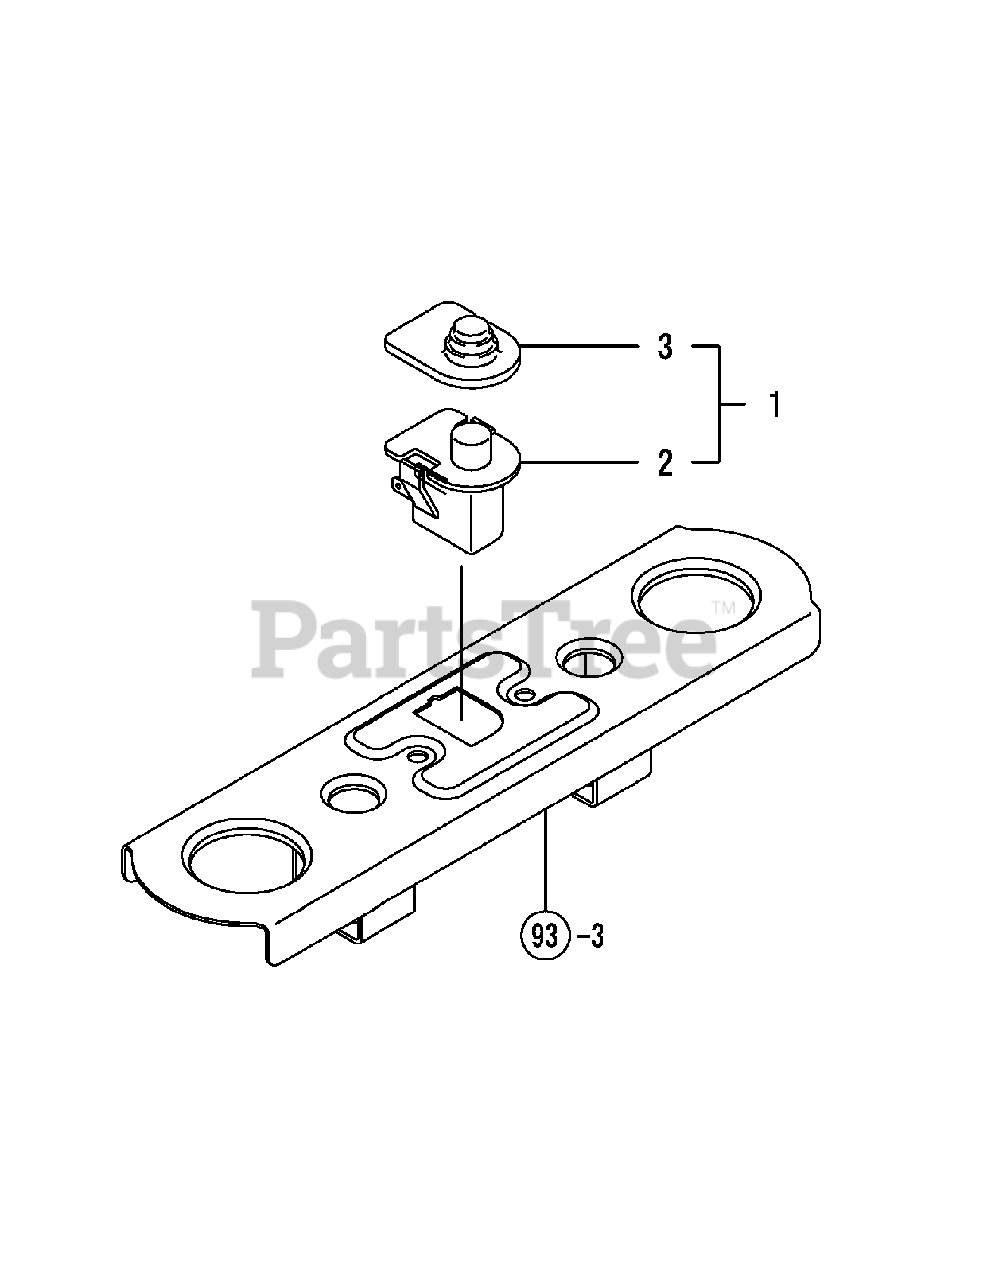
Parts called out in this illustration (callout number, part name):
1	SWITCH,SEAT,DELTA,AS
2	SWITCH,SEAT,DELTA,AS
3	PROTECTIVE COVER,
